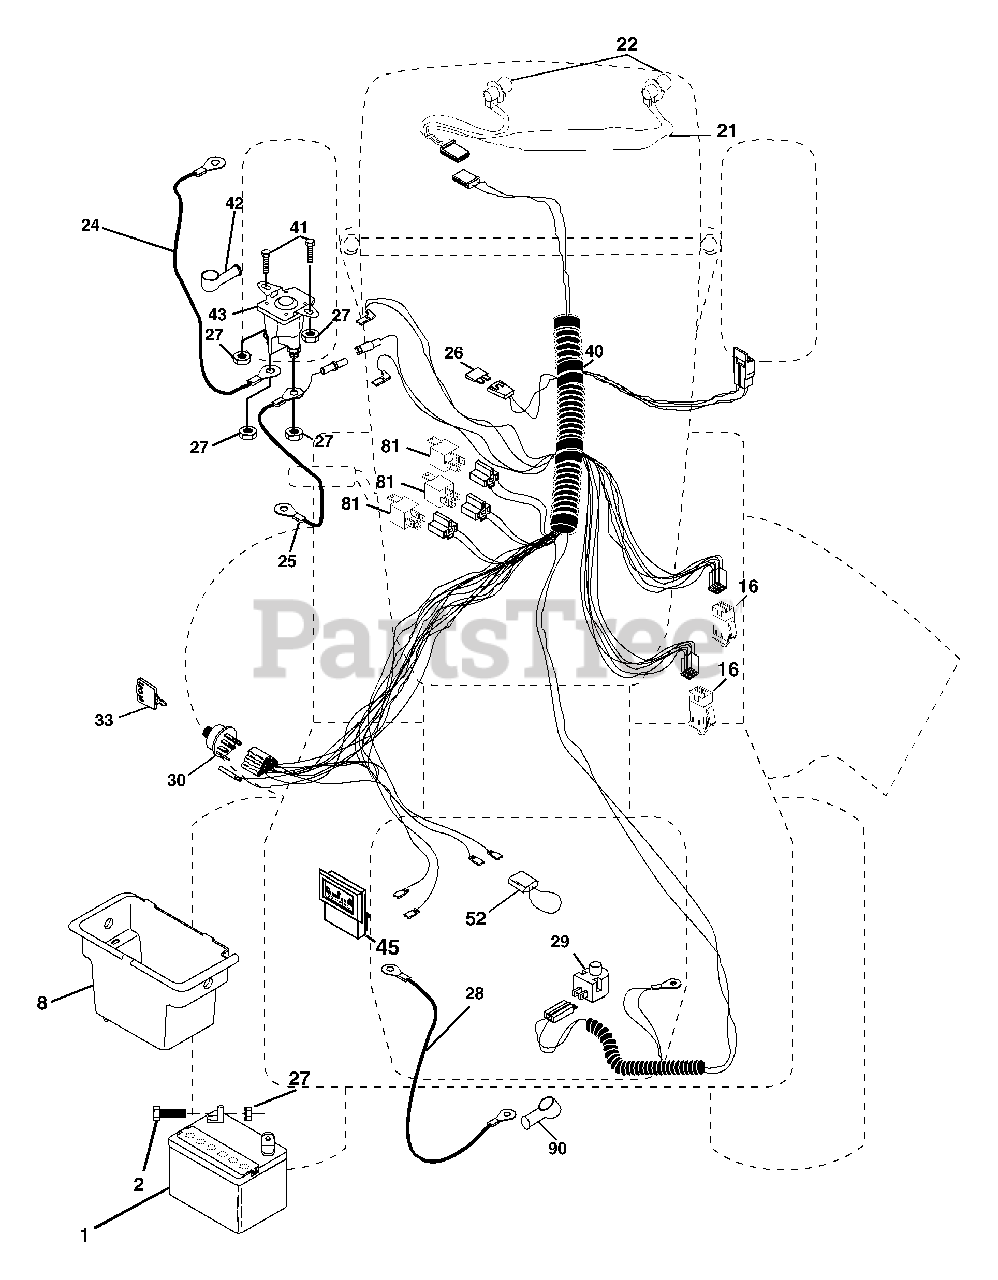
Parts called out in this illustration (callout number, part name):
1	Battery 12 Volt 25 Amp
2	Bolt Hex Hd 1/4-20unc X 3/4
8	Box Battery
16	Switch Interlock
21	Harness Asm Light W/4152J
22	Bulb Light #1156
24	Cable Battery 6 Ga 11" red
25	Cable Battery 6 Ga w/16 wire,red
26	Fuse 20 AMP
27	Nut Keps Hex 1/4-20 unc
28	Cable Ground 6 Ga 12" black
29	Switch Plunger
30	Switch Ign
33	Key Ign
40	Harness Ign
41	Bolt Blk Fin Hex 1/4-20 X 1/2
42	Cover Terminal Red
43	Solenoid
45	Ammeter
52	Protection Wire Loop
81	Relay Asm.
90	Cover Terminal
